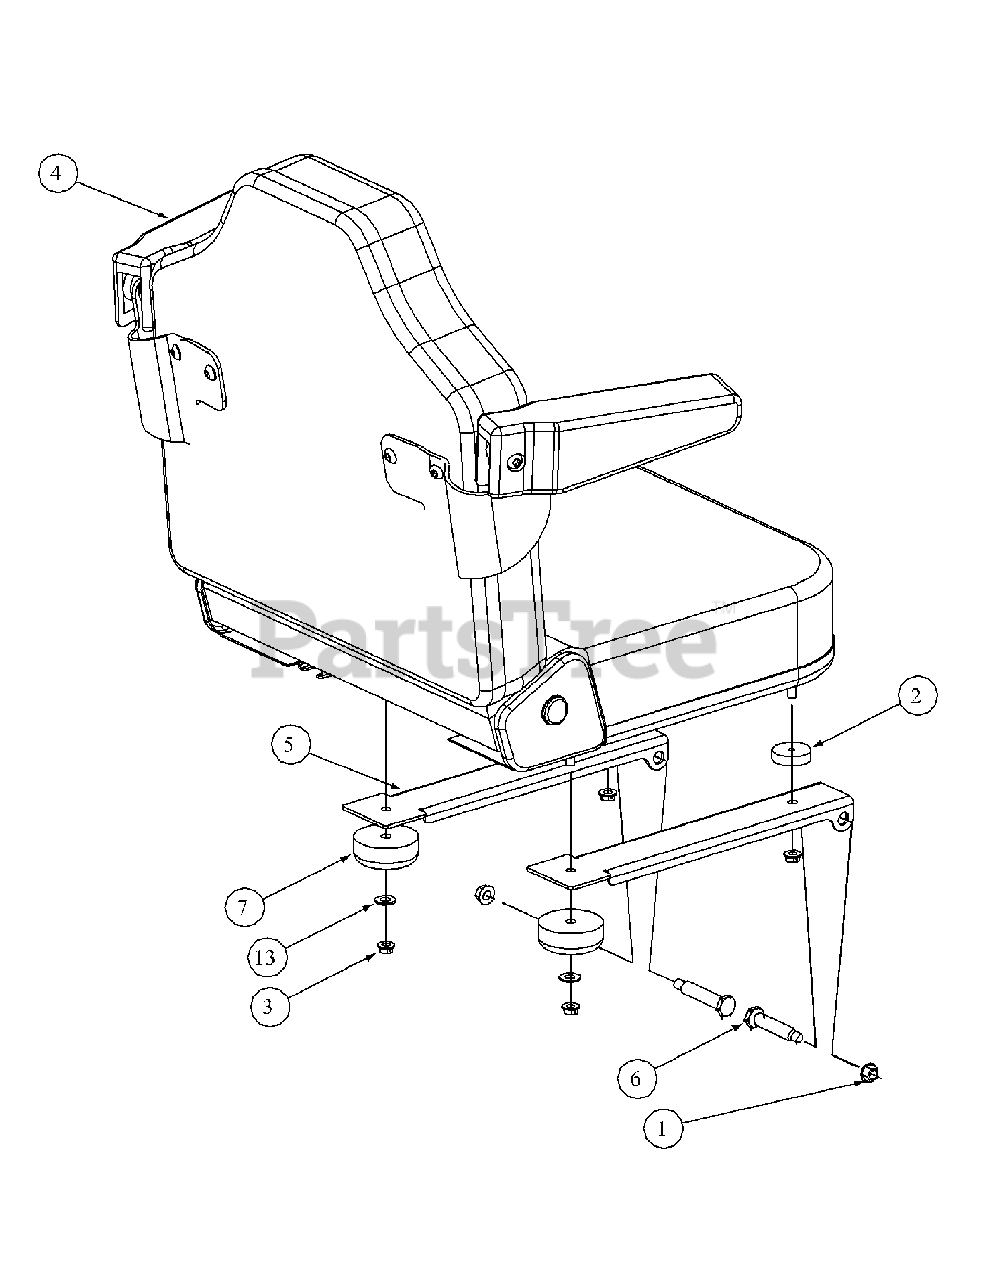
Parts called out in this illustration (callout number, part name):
1	Nut, Hex 3/8-16 Flange Lock
2	Spacer, 0.345 ID x 1.50 OD x .41
3	Lock Nut, Hex Flange, 5/16-18
4	Adjustable Seat, Black embossed, Forward Fold
5	Mounting Bracket, Seat
6	Shoulder Screw, .50x2.345, 3/8-16
7	Grommet, 2.5 OD x 1.0 Long
13	Washer, .325 ID x .930 OD x .045
